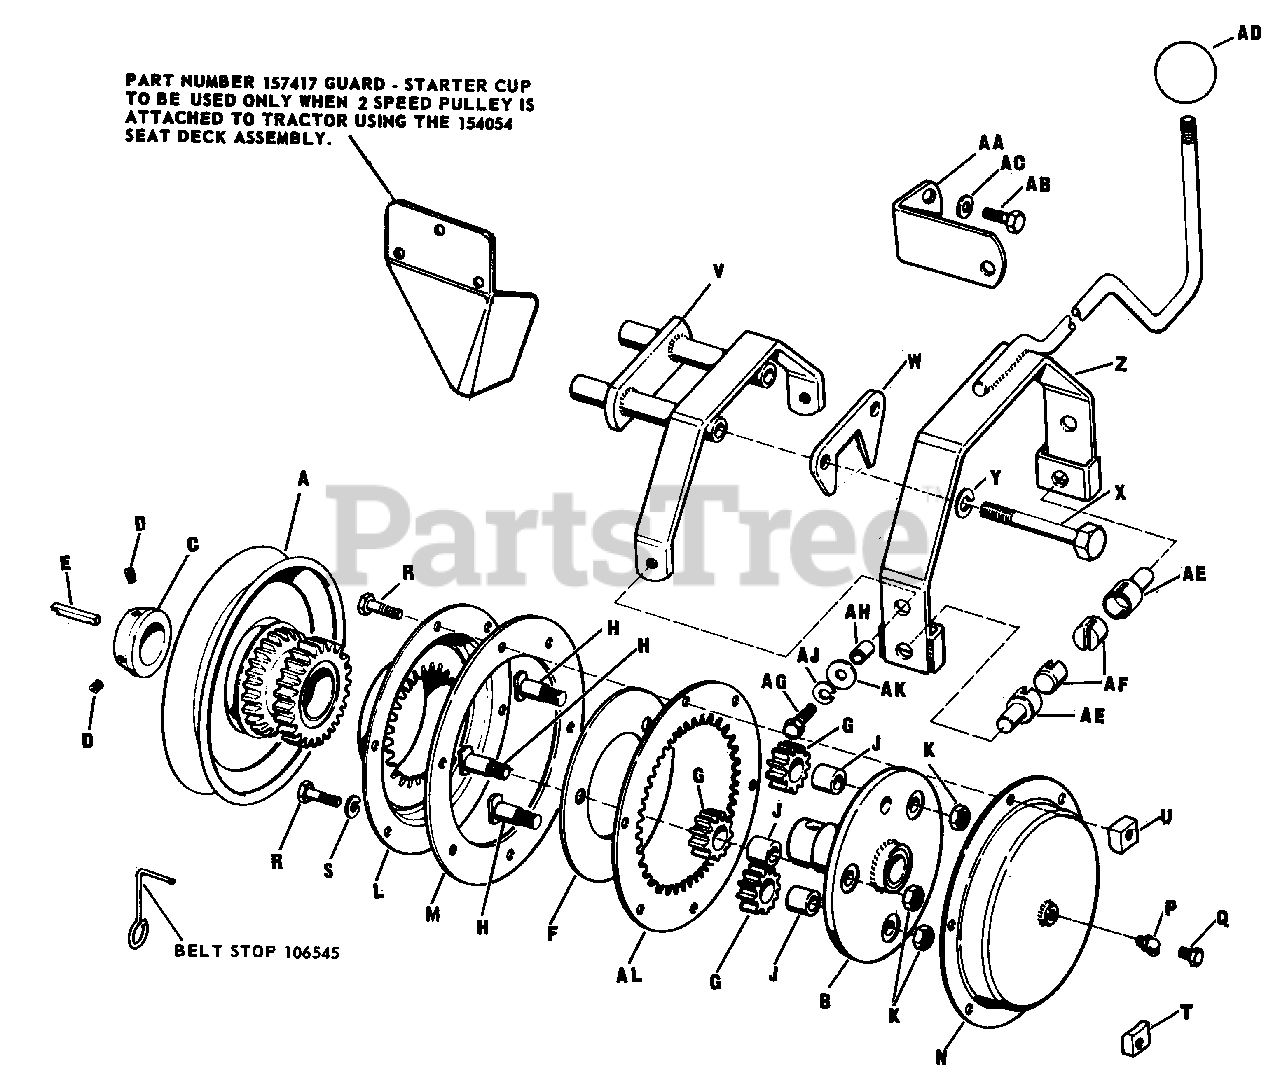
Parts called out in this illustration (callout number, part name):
A	Pulley & Gear Ass'y.
B	Spider & Brg. Ass'y.
C	Set Collar
D	Set Screw 5/16"-18 N.C. x 3/8"
F	Ring, Bolt
J	Needle Bearing
K	Full Lock Nut, Hex., 5/16"-18 N.C.
L	Cover Ass'y. L.H.
M	Shift Ring
N	Cover Ass'y R.H.
P	Grease Fitting
Q	Hex., Cap Screw 1/4"-28 N.F. x 1/2
R	Hex Cap Screw 5/16"-18 N.C. x 5/8"
S	Lock Washer 5/16"
T	Special Nut
U	Special Nut
V	Support Ass'y, Shift
Y	Lock Washer 5/16"
Z	Fork Ass'y. Shift
AA	Support, Shift Rod
AB	Hex. Cap Screw 1/4"-20 N.C. x 1"
AC	Lock Washer, 1/4"
AF	Bearing, Pivot
AG	Hex. Cap Screw 1/4"-20 N.C. x 3/4"
AJ	Lock Washer, 1/4"
AK	Washer Plain 1/4"
AL	Gear Ring.
